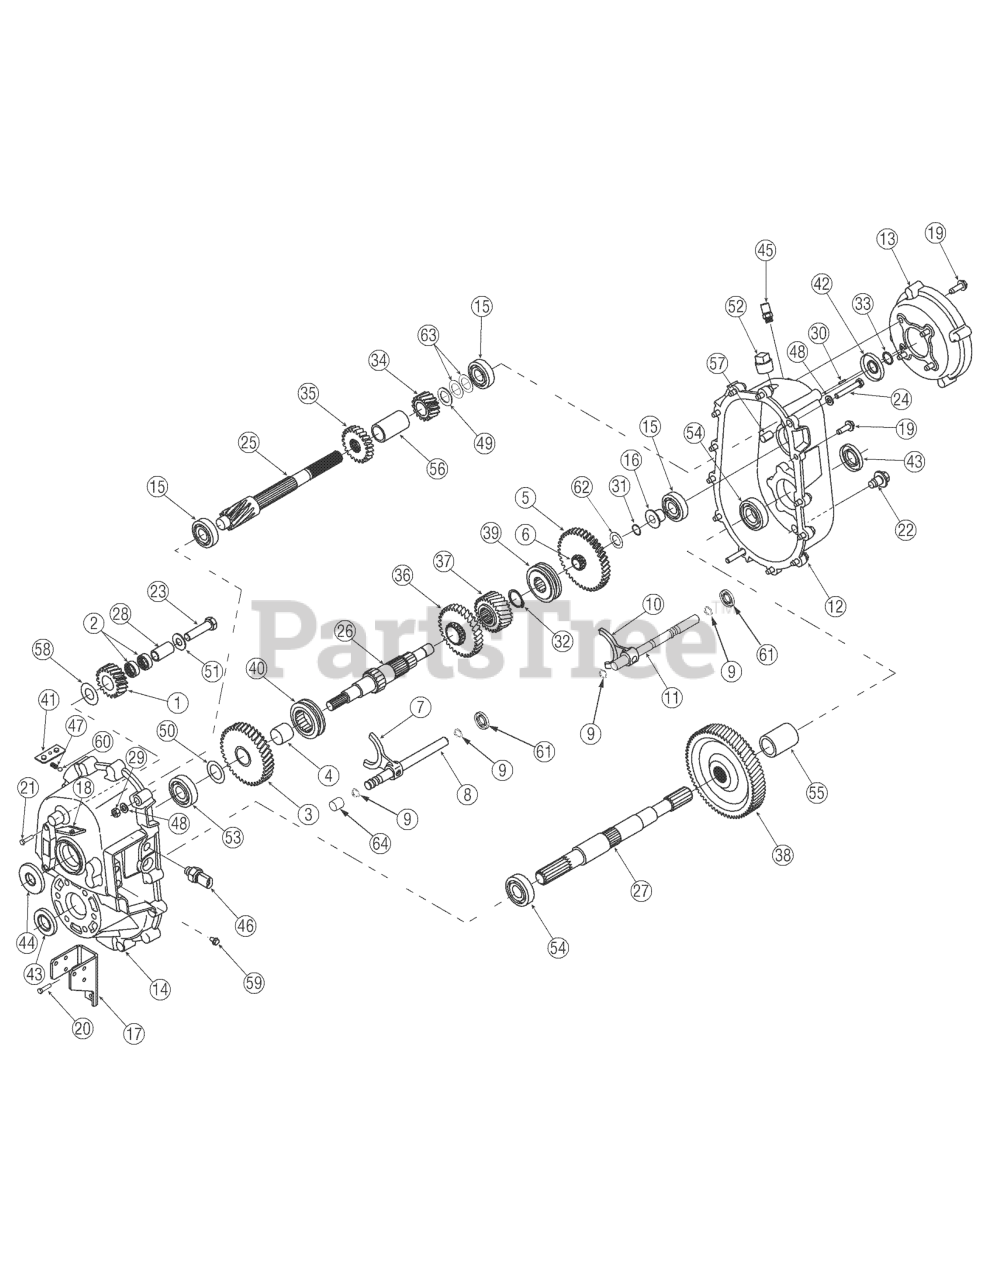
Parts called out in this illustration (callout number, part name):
1	Gear, Rev Idler, 19T
2	Brg., Needle,.7500 x 1.0 x .375
3	Gear, Rev, 39T
4	Brg, Slv, 25mm x 28mm x 25mm
5	Gear, Lo, 40T
6	Brg, Slv, 16 x 18 x 10
7	Yoke, Actr.
8	Shf, Actr, Fwd, Rev
9	Ring, Ret, .56 Dia.
10	Yoke, Actr, 4WD
11	Shf, Actr, Lo
12	Hsg, lh, 4x4 Uv
14	Hsg Assembly, rh, uv, 4x4
14	Plug, M14 x 1.5 x .827
15	Brg, ball, 20 x 47 x 14, 6204, open
16	Spcr, Flg,l630 x .787 x .662
20	Scr, Id, 5/16-18, 0.750, hxindwsh
21	Scr, soc Hd, 5/16-18, .750
22	Scr, plug, m14x1.5 Magnetic
23	Hhcs, 1/2-13, 2.00, gr8, std
24	Hhcs, 5/16-18, 2.00, gr5, std
25	Shf, input, 4x4 Transfer Case
26	Shf, mid, 4x4 Transfer Case
27	Shf, output, 4x4 Transfer
28	Shf, rev Idler
29	Nut, hexlk, 5/16-18, gra, ctrlk
30	Pin, roll, 1/8 Od, .63
31	Ring, external snap, .625 Dia Shaft
32	Ring, ret, 1.125 Dia Shaft
33	Ring, wire, 20mm Shaft
34	Gear, low Pinion, 4x4, 15t
35	Gear, high Pinion, 4x4, 22t
36	Gear, high, 4x4, 33t
37	Gear, final Pinion, 4x4, 22t
38	Gear, final, 4x4, 73t
40	Colr, hi-rev, 4x4
41	Plt, detent Spring
42	Seal, oil, 20 X 47 X 7
43	Seal, oil, 25x46x7
44	Seal, oil, 20x52x7
45	Creeper Drive Housing Breather
46	Sw, neut, saf
47	Spr, 3/8 Od X 1 1/4 Lg
48	Wash, flat, .330 x .630 x .0635
49	Wash, flat, l739 x 1.24 x .06, ht
50	Wash, flat, 1.007x1.542x.03, ht
51	Wash, flat, .51 x 1.12 x .06, ht
52	Plug, pipe, 3/4 Nptf
53	Brg, ball, .79 ldx 2.05 Od x .6
54	Brg, ball, 25x52x15, 6205, open
55	Spcr, output Shaft, 4x4
56	Spcr, mid Shaft, 4x4
57	Bushing, Dowel
58	Wash, thrust, .757x1.38x.062
59	Scr, tt,1/4-20x.625, hxindwah,ca
60	Ball, detent, .375
61	Seal, Oil, .583x.875x.188
62	Washer, Flat, .635x.93x.033 HT
63	Washer, Shim - As Required
64	Spacer, .566 x .725 x 65
